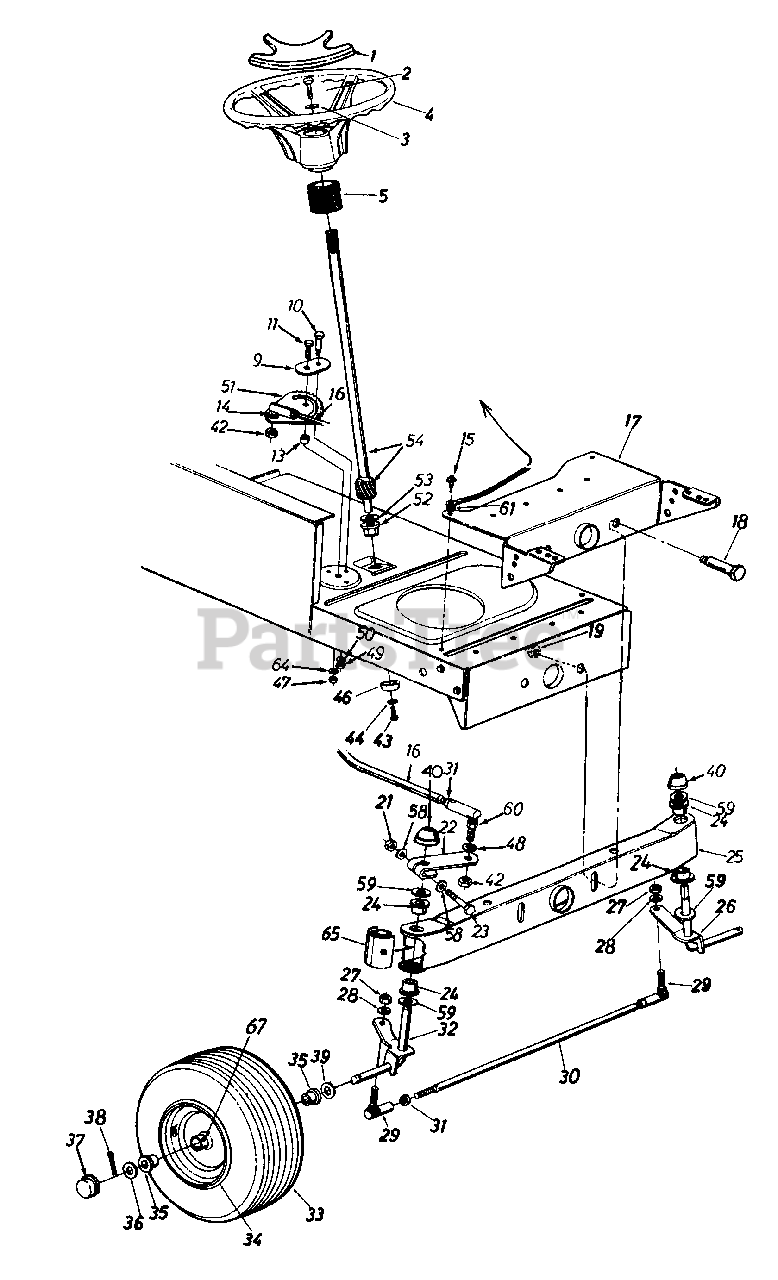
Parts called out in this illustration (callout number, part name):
1	Steering Wheel Cap
2	Hex Bolt 5/16-18 x 1" Lg.
3	Belleville Wash. .345" I.D.
4	Steering Wheel
5	Steering Bellow - 9"
9	Retainer Plate
10	Shoulder Bolt .437" Dia. x .35" Lg. - 5/16-18 Thd.
11	Hex Bolt 3/8-24 x 1.0" Lg. (Grade 5)
13	Spacer .380" I.D. x .625" O.D. x .227
14	L-Wash. 3/8" I.D. (H.D.)
15	Hex Wash. Hd. Self-Tap Scr.
16	Steering Drag Link
18	Shoulder Bolt .498" Dia. x 2.04" Lg. - 3/8-16 Thd.
19	Flanged Hex Nut 3/8-16 Thd.
21	Hex L-Nut 5/16-24 Thd.
22	Steering Arm Front Axle
23	Hex Bolt 5/16-24 x 2.00" Lg. (Grade 5)
24	Hex Flg. Brg..632 I.D.
26	Front Axle Ass'y. - L.H.
27	Hex Nut 3/8-24 Thd.
28	L-Wash. 3/8" I.D.
29	Ball Joint 3/8-24 Thd.
31	Hex Jam Nut 3/8-24 Thd.
32	Front Axle Ass'y. - R.H.
36	Fl-Wash. .635" I.D. x 1.59" O.D.
37	Hub Cap
38	Cotter Pin 1/8" Dia. x 1.25"
39	Fl-Wash. .640" I.D. x 1.24" O.D.
40	Push Cap 5/8" Dia. Rod
42	Hex Jam Nut 3/8-24 Thd.
43	Torx Bolt 5/16-18 x .63" Lg.
44	L-Wash. 5/16" I.D.
46	Cap 1.25" x .16"
47	Hex Cent. L-Nut 3/8-24 Thd.
49	Hex Cent. L-Nut 5/16-18 Thd.
50	L-Wash. 5/16" I.D.
51	Steering Gear Segment
52	Hex . Flg. Brg. 5/8" I.D.
53	Fl-Wash. (Hardened)
54	Steering Shaft
58	Wave-Wash. .32" I.D. x .62" O.D.
59	Fl-Wash. (Hardened)
60	Drag Link Ball Joint 3/8-24 Thd.
61	Ext. L-Wash. 5/16" I.D.
64	Bell-Wash. .39" I.D. x 1.38" O.D.
65	Pivot Bar End Cap
67	Grease Fitting
